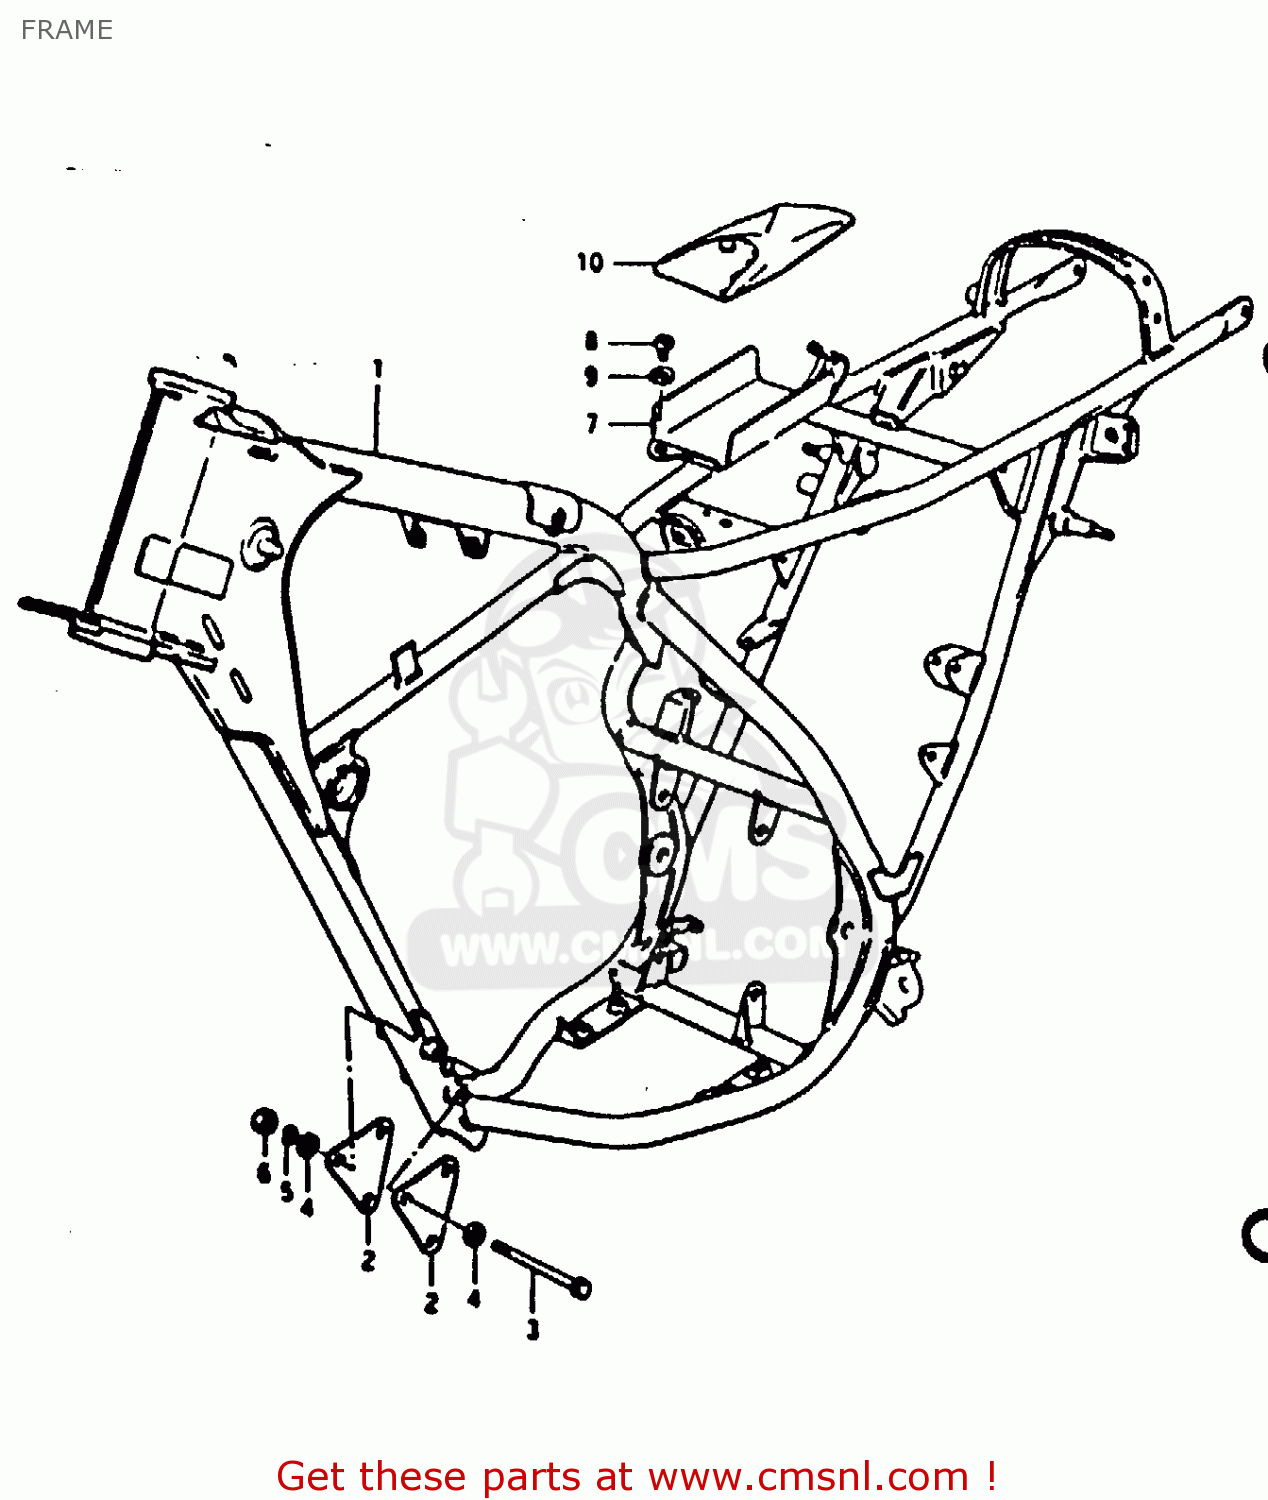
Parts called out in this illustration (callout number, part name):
1	1-2
2	2-2
3	BOLT,8X75
4	WASHER
5	LOCK WASHER
6	NUT
7	HOLDER,TOOL
8	SCREW
9	WASHER
10	TOOL ASSY
